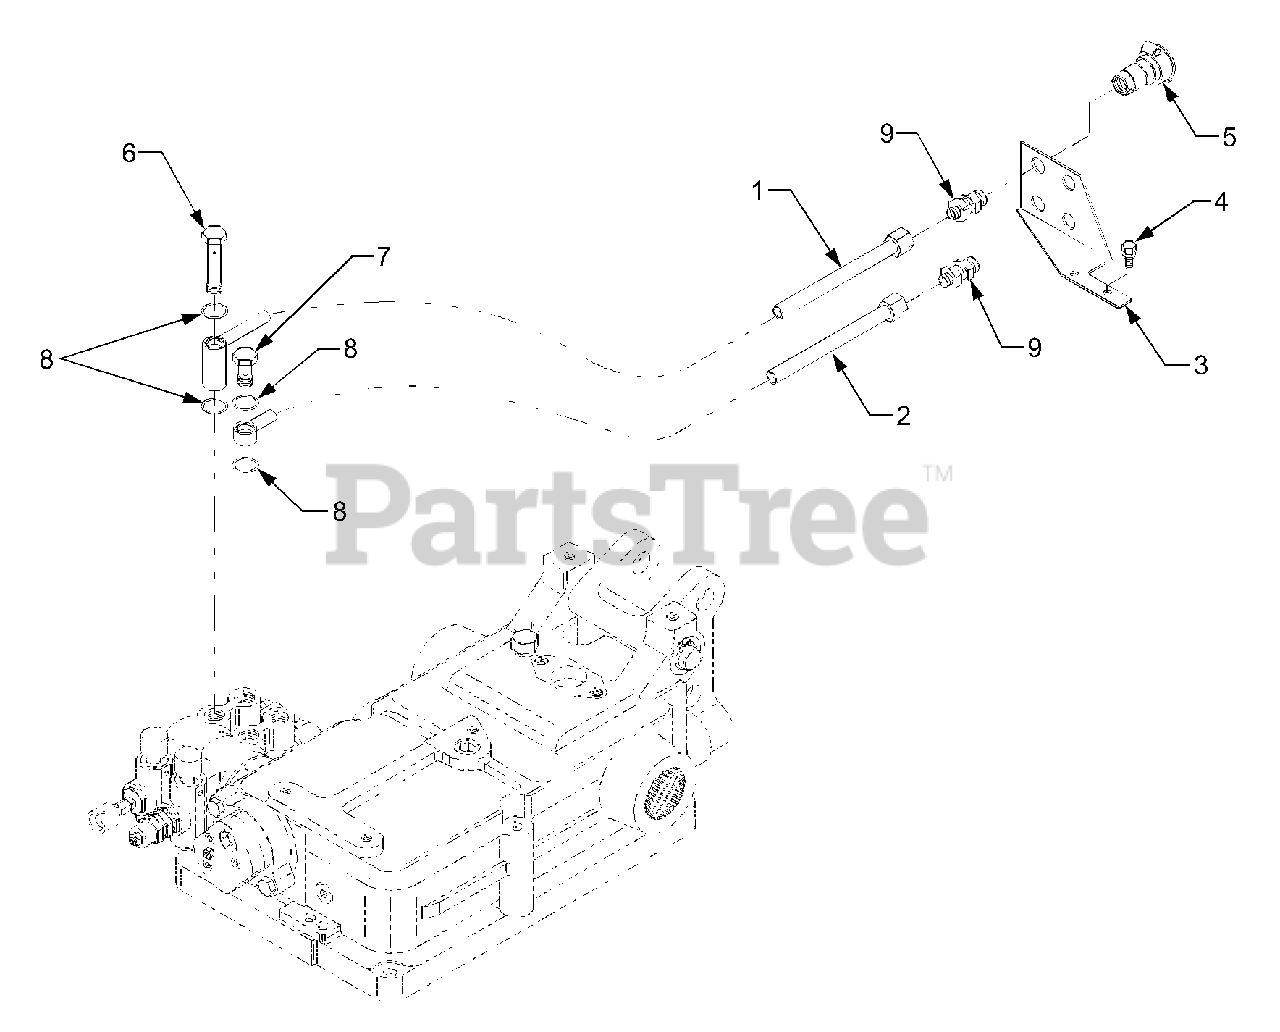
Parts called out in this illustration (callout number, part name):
1	Pipe A, Hydraulic
2	Pipe B, Hydraulic
3	Bracket, Scoket
5	Coupler Socke Ass'y
6	Bolt 3, Joint
7	Bolt 2, Joint
9	Connection, Filter
